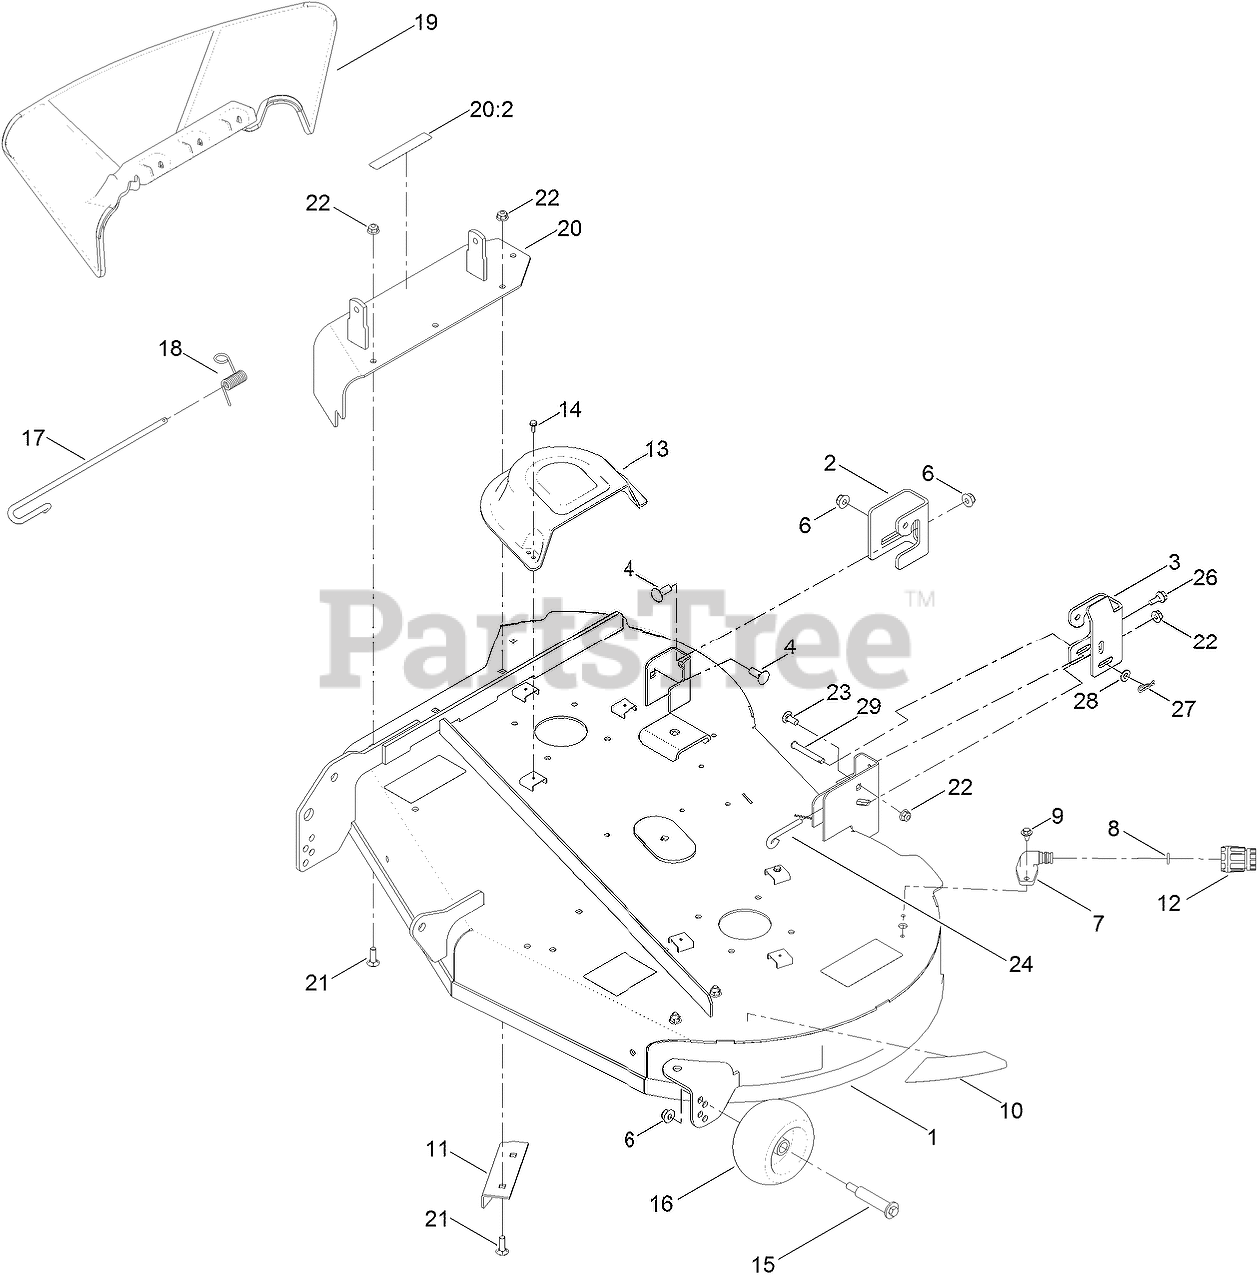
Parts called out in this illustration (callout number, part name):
1	42 INCH DECK ASM
2	BRACKET-HANGER, RH
3	BRACKET-HANGER, LH
4	BOLT-CARR
6	NUT-HF, NI
7	FITTING-WASHOUT
8	O-RING
9	SCREW-HHFTF
10	DECAL-DECK
11	BAFFLE-CUTOFF
12	CONNECTOR-HOSE
13	COVER-BELT
14	SCREW-TAPTITE
15	BOLT-SHOULDER
16	ROLLER-SCALP, ANTI
17	PIN-CHUTE
18	SPRING-TORSION
19	DEFLECTOR-DISCHARGE
20	COVER ASM W/DECAL
20:2	DECAL-DANGER
21	SCREW-CARR
22	NUT-HF, NI
23	SCREW-CARR
24	ROD-LEVEL, DECK
26	SCREW-SHOULDER, HHF
27	PIN-COTTER
28	WASHER-PLAIN
29	PIN-CLEVIS
